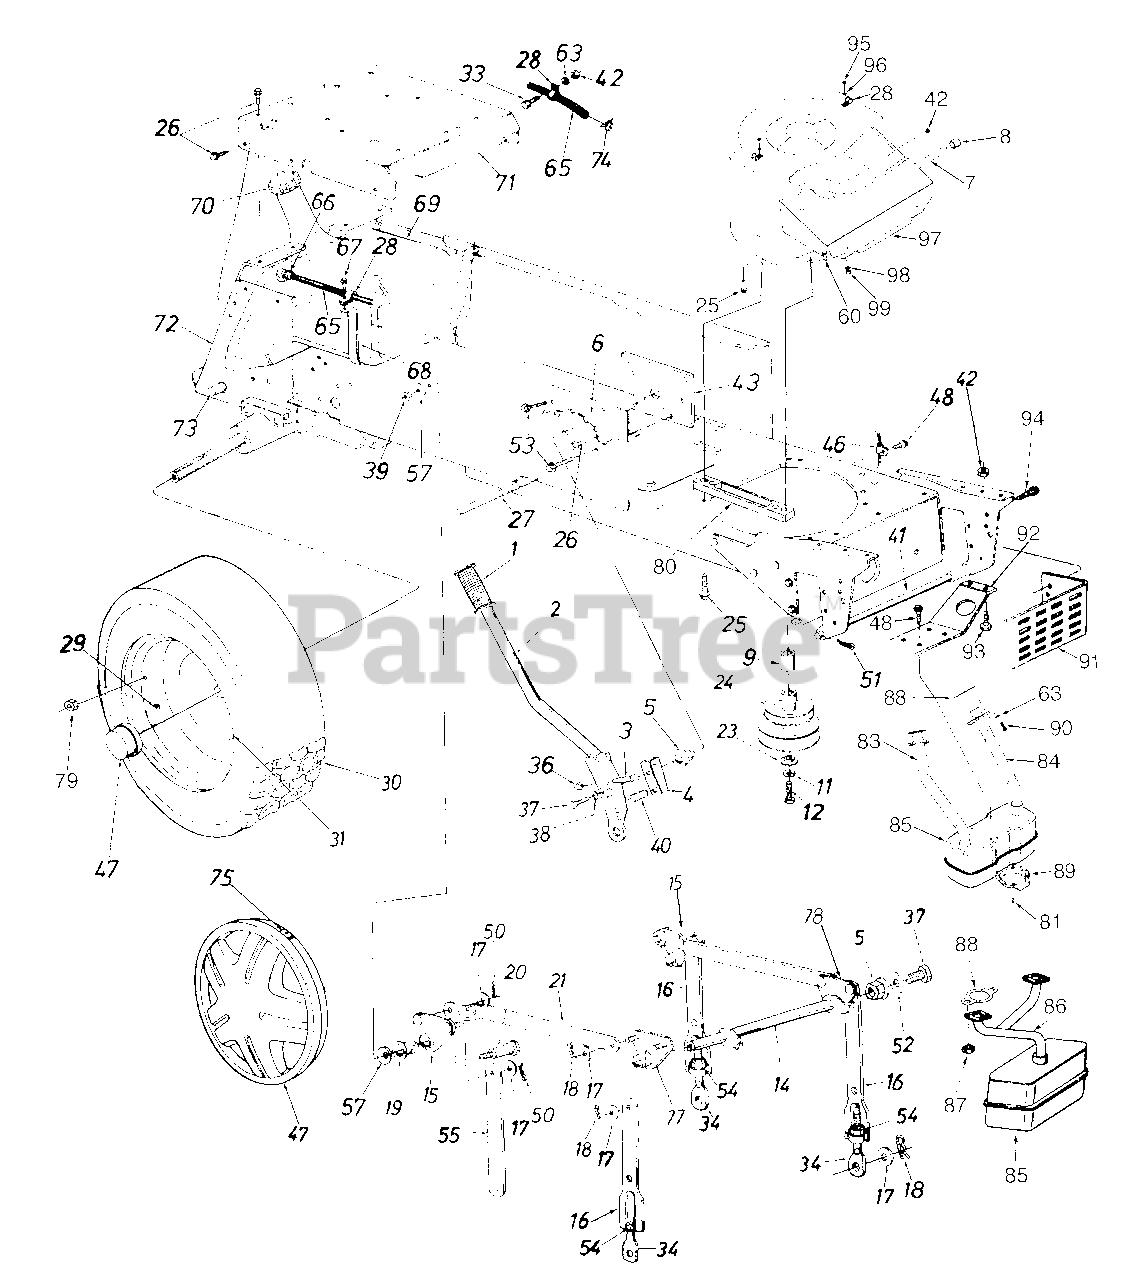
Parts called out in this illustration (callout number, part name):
1	Grip
4	Lift Shaft Drive
5	Plastic Hex Brg. 5/8" I.D.
8	Pipe Cap 3/8-18 Npt.
9	Spacer
11	L-Wash. 7/16" I.D.
12	Hex Scr. 7/16-20 x 2" Lg. (Gr. 5)
14	Lift Shaft Ass'y.
15	Lift Pivot Brkt. Ass'y.
17	Fl-Wash. 1/2" I.D. x 1.00" O.D. x .090"
18	Hairpin Cotter
19	Nyliner 5/8" I.D. x .88" Lg.
20	Shld. Bolt 5/8" Dia. x .96" Lg. 3/8-16
24	Engine Pulley
25	Hx Wash Hd. Scr. 3/8-16 x 1.25" Lg.
26	Hex Thd. Rolling Scr. 5/16-18 x .75" Lg.
27	Running Board Rod
28	Clamp
29	Air Valve
33	Hex Bolt 1/4-20 x .62" Lg.
34	Eye Bolt Adj. Link 1/2-13 Thd.
36	Hex Cent. L-Nut 5/16-18 Thd.
37	Hex Bolt 5/16-24 x .62" Lg.
38	L-Wash. 5/16" I.D.
39	Hex Top L-Nut 3/8-16 Thd.
40	Compression Spring
41	Deck Connecting Rod
42	Hex Sems Nut 1/4-20 Thd.
47	Hub Cap
48	Hx Wash Hd. TT-Tap Scr. 1/4-20 x .5" L
50	Cotter Pin .09 Dia. x 1.0" Lg.
51	Int. Cotter Pin
52	Fl Wash. .34" I.D. x 1.12" O.D. x .125"
53	Hx Wash Hd AB-Tap Scr 5/16-24 x .5" L
54	Hex Nut 1/2-13 Thd.
57	Bell-Wash. .4" I.D. x 1.13" O.D.
60	Hex Bolt 5/16-18 x .75" Lg.
63	L-Wash. 1/4" I.D.
65	Fuel Line 46" Lg.
66	Hose Clamp
67	Hex AB-Tap Scr. 1/4 x .62" Lg.
68	Fuel Tank Strap
69	Gas Tank
70	Gas Gauge
71	Seat Plate
74	Hose Clamp
75	Spring Clip
77	Pivot Brkt. Ass'y.--R.H.
78	Pivot Brkt. Ass'y.--L.H.
79	Lug Nut 7/16-14 Thd.
80	Engine Mounting Spacer
81	Hex Hd. F-Tap Scr. #8-32 x .38" Lg.
83	Exhaust Tube--R.H.
84	Exhaust Tube--L.H.
85	Muffler
86	Exhaust Pipe
87	Flange Nut M8 x 1.25 Thd.
88	Exhaust Gasket
89	Muffler Deflector
90	Hex Bolt 1/4-20 x .75" Lg.
93	Hex Bolt 1/4-20 x .62" Lg.
94	Hex TT-Tap Scr. 5/16-18 x .62" Lg.
95	Truss Mach. B-Tap Scr. #10 x .5" Lg.
96	Fl-Wash. .188" I.D. x .438" O.D.
99	Hex Nut 5/16-18 Thd. (Gr. 5)
